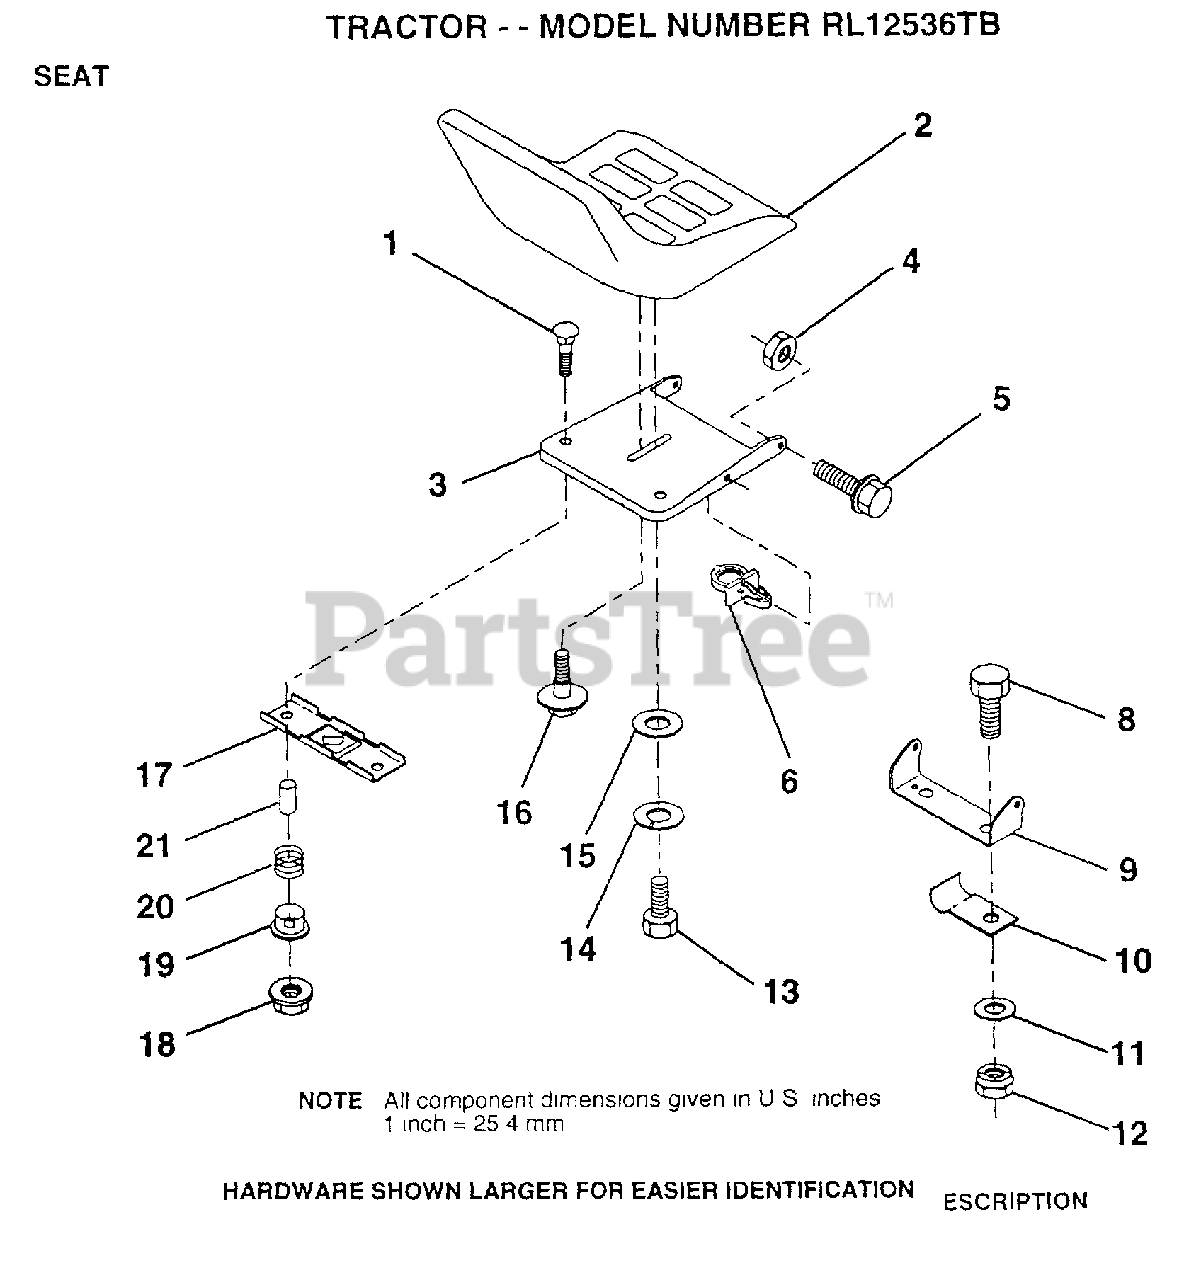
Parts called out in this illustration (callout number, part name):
4	NUT
5	"BOLT,SHOULDER"
6	CLIP.PUSH-IN.HING
8	BOLT
9	BRACKET PVT SEAT
10	"CLIP,INSULATOR"
11	WASHER
12	NUT
13	BOLT
14	LOCKWASHER
15	WASHER
16	"BOLT,SHOULDER"
17	BRKT SWITCH
19	BUSHING
20	SPRING
21	SPLIT SPACER
